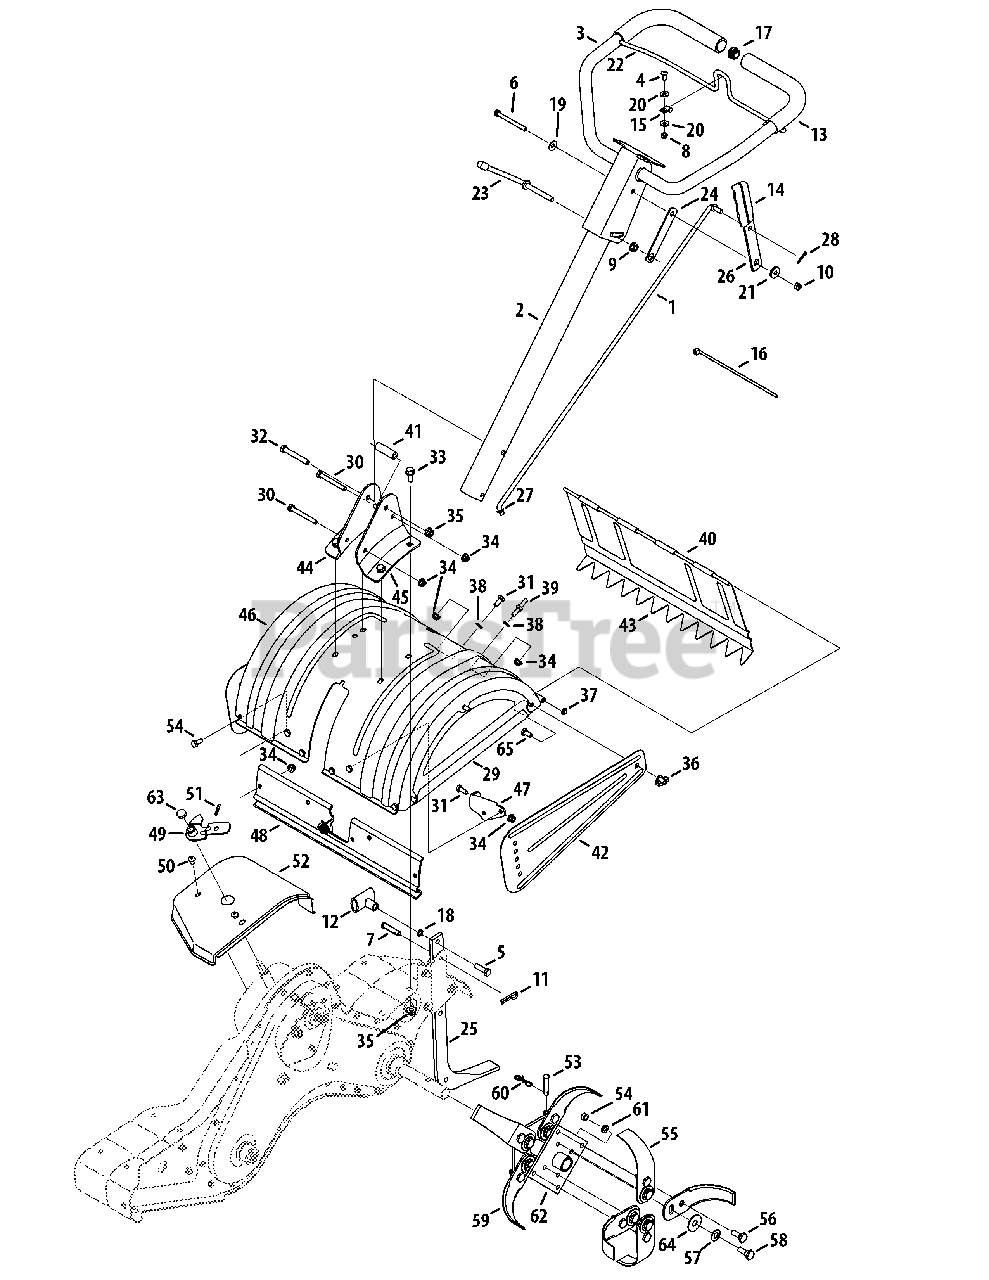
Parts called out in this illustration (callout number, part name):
1	Shift Rod
2	Lower Handle Ass’y
3	Upper Handle Ass’y
4	Screw 1/4-20 x .625
5	Hex Bolt 3/8-16 x 1.25
6	Hex Bolt 5/16-18 X 3.25
7	Clevis Pin 3/8 Dia
8	Hex L-Nut 1/4-20
9	Hex Flange Nut 3/8-24 Thd.
10	Hex Ins. L-Nut 5/16-18
11	Hairpin
12	Small "T" Knob
13	Grip (2 req’d)
15	Battery Clamp
16	Cable Tie
17	Vinyl End Plug
18	Flat Washer .385 ID X .62 OD X .033
19	Bell. Washer .345 ID X .88 OD X .06
20	Flat Washer .260 x .720 x .060
21	Shoulder Spacer
22	Bail Clutch
23	Handle Adj. Crank
24	Bracket Hex Nut Retainer
25	Depth Bar
26	Shift Lever Rod
27	Rubber Washer .33 ID x .125
28	Int. Cot ter Pin 5/16 Dia.
29	Tine Shield Cover Ass’y
30	Hex Scr 5/16-18 X 2.75
31	Hex Bolt 5/16-18 x .75" Lg. Gr. 5
32	Hex Screw 3/8-16 x 2.75" Lg.
33	Carriage Bolt 3/8-16 x .875" Lg.
34	Flanged Lock Nut 5/16-18 Gr. 5
35	Flange Lock-Nut 3/8-16 Gr. F Ny lon
36	Wing Nut
37	Push Cap
38	Flat Washer .34 ID X .62 OD X .03
39	Hex Screw 5/16-18 x .75
40	Tiller Flap Rod
41	Spacer .322 ID x .47 OD
42	Side Shield
43	Rear Tine Shield
44	RH Handle Brkt.
45	LH Handle Brkt.
46	Tine Shield
47	Tine Shield Brkt.
48	Shoulder Spacer Brkt.
49	Shift Crank Ass’y
50	Torx Mach. AB-Tapp Scr. 1/4 X .62" Lg.
51	Spring Pin Roll 3/16 Dia.
52	Shift Cover
53	Clevis Pin 3/8 Dia
54	Hex L-Nut 3/8-24 (Grade 5)
55	13" Dia. Articulating Tine
56	Shld. Scr. 1/2 Dia. x .175
57	Belleville washer .505 ID X 1.00 OD X .0
58	Shld. Bolt 1/2" Dia. x .320
59	Tine Adapter Assembly, 18"
59	Tine Assembly
60	Bow Tie Cotter Pin
61	L-Wash 3/8 ID
62	Tine Adapter Plate
64	Stud, 5/16-18 x .75
